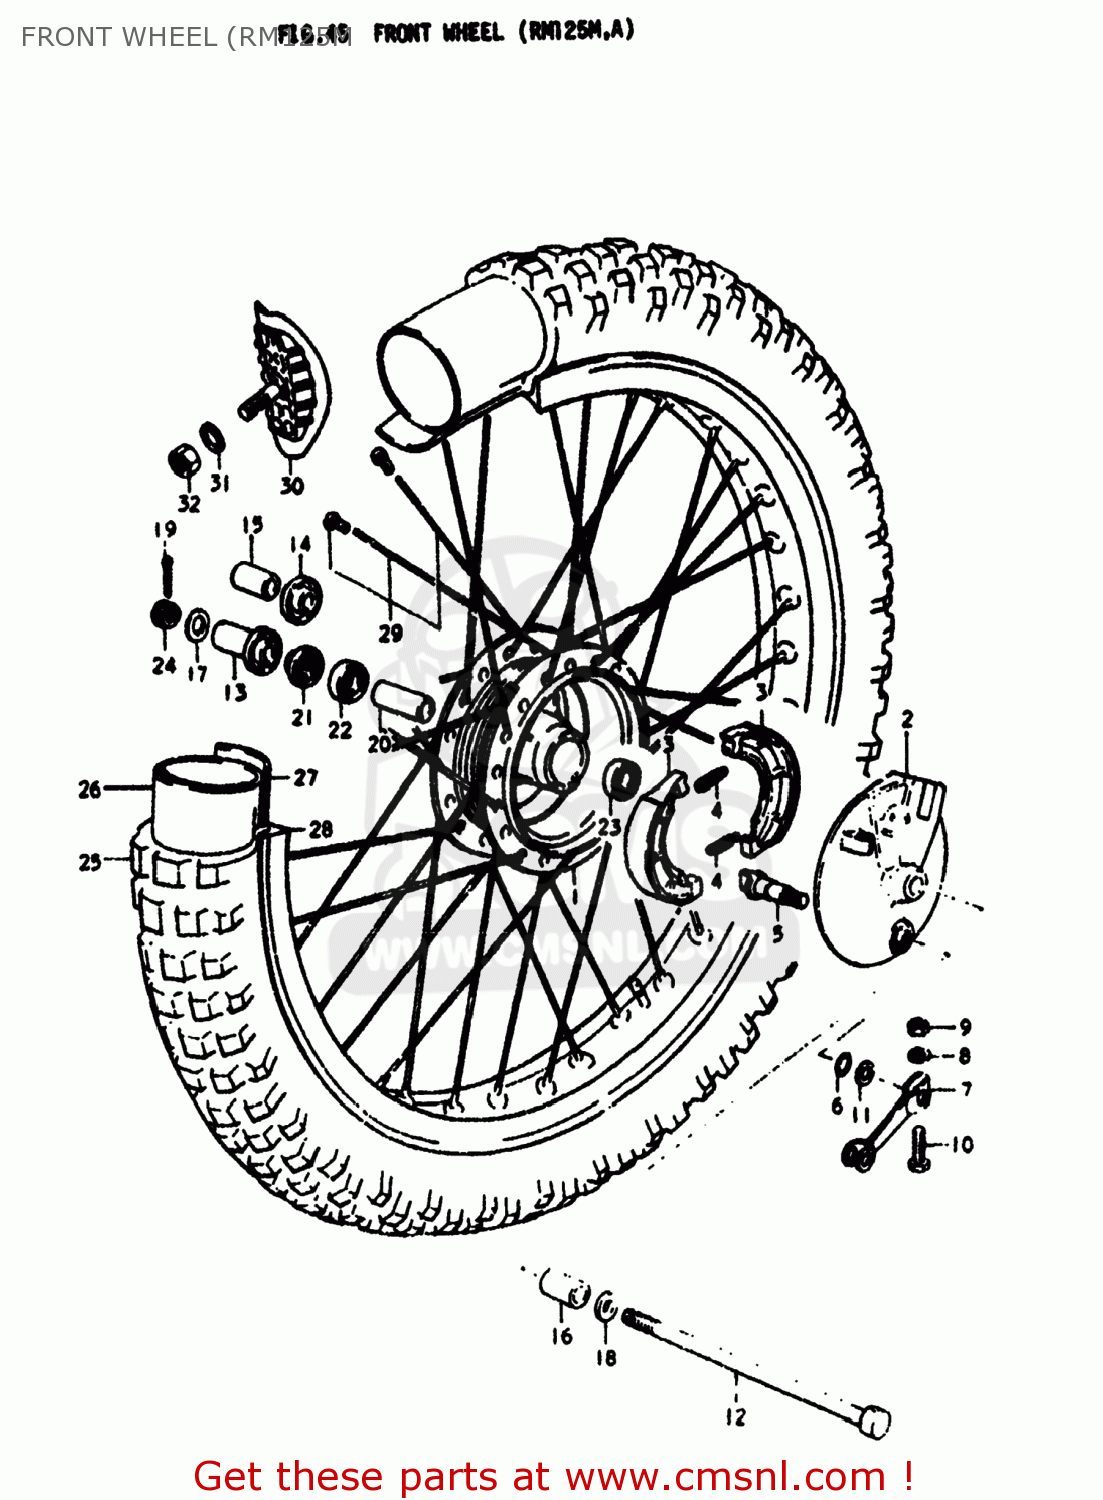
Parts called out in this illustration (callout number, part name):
1	HUB,FRONT
2	PANEL,FRONT HUB
3	SHOE,BRAKE
4	SPRING(L:34)
5	CAM,FR BRAKE
6	O RING(D:2.5,ID:11.4)
7	LEVER,FRONT BRAKE CAM
8	WASHER
9	NUT
10	BOLT
11	WASHER(12.5X20X1)
12	AXLE,FRONT
13	SPACER,FRONT AXLE,RIGHT
14	SPACER,FRONT AXLE,RIGHT
15	SPACER
16	SPACER(12X20X34.5)
17	WASHER
18	SPACER
19	COTTER PIN
20	SPACER,FRONT HUB BEARING
21	OIL SEAL(17X38X5)
22	BEARING
23	BEARING, RH
24	NUT 12MM
25	TIRE,FRONT
26	TUBE
27	PROTECTOR,WHEEL,INNER
28	RIM,FRONT WHEEL
29	SPOKE SET
30	STOPPER,BEAD
31	WASHER
32	NUT
